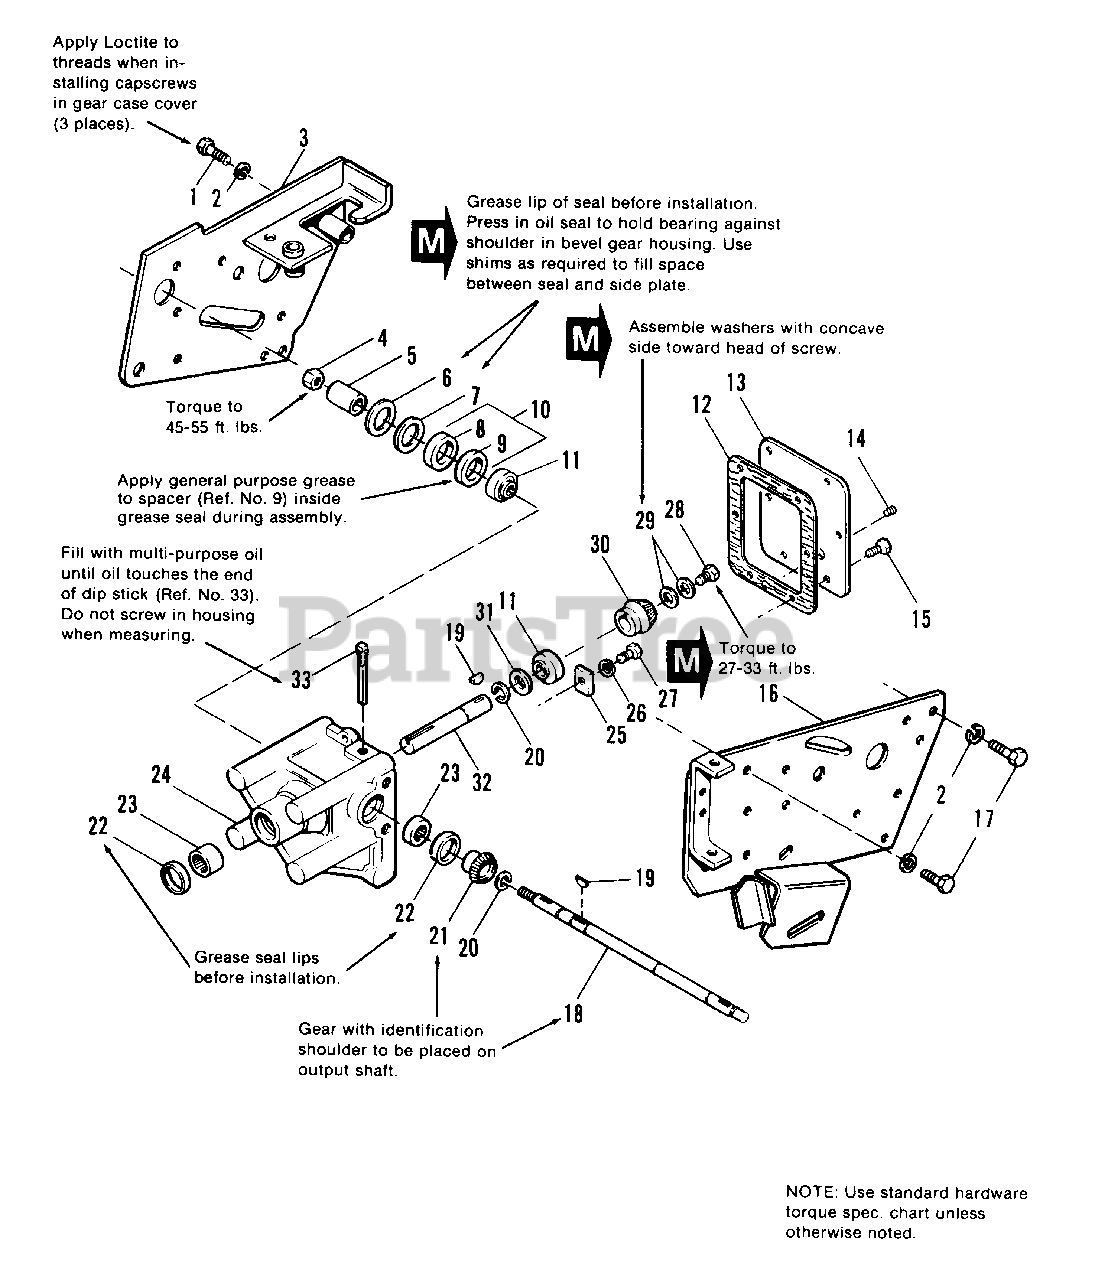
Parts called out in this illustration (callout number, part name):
1	CAPSCREW, Hex Hd., 7/16-14 x 1
2	LOCKWASHER, 7/16
3	PLATE ASSY., Side, R.H.
4	LOCKNUT, Hex, Jam, 3/4-16
10	REPAIR KIT, Seal
11	BEARING, Ball
14	PLUG, Pipe (if equipped)
15	CAPSCREW, Hex Hd., 1/4-20 x 5/8
16	PLATE ASSY., Side, L.H.
17	CAPSCREW, Hex Hd., 7/16-14 x 1-1/4
18	SHAFT, Driven
19	KEY, Woodruff, #9
20	RING, Retaining
21	GEAR, Bevel, Driven
23	BEARING, Needle
24	HOUSING, Bevel Gear
25	PLATE, Bearing Clamp
26	LOCKWASHER, 5/16
27	CAPSCREW, Hex Hd., 5/16-18 x 5/8
28	CAPSCREW, Hex Hd., 5/16-18 x 3/4
30	GEAR, Bevel, Driven
32	SHAFT, Driver
